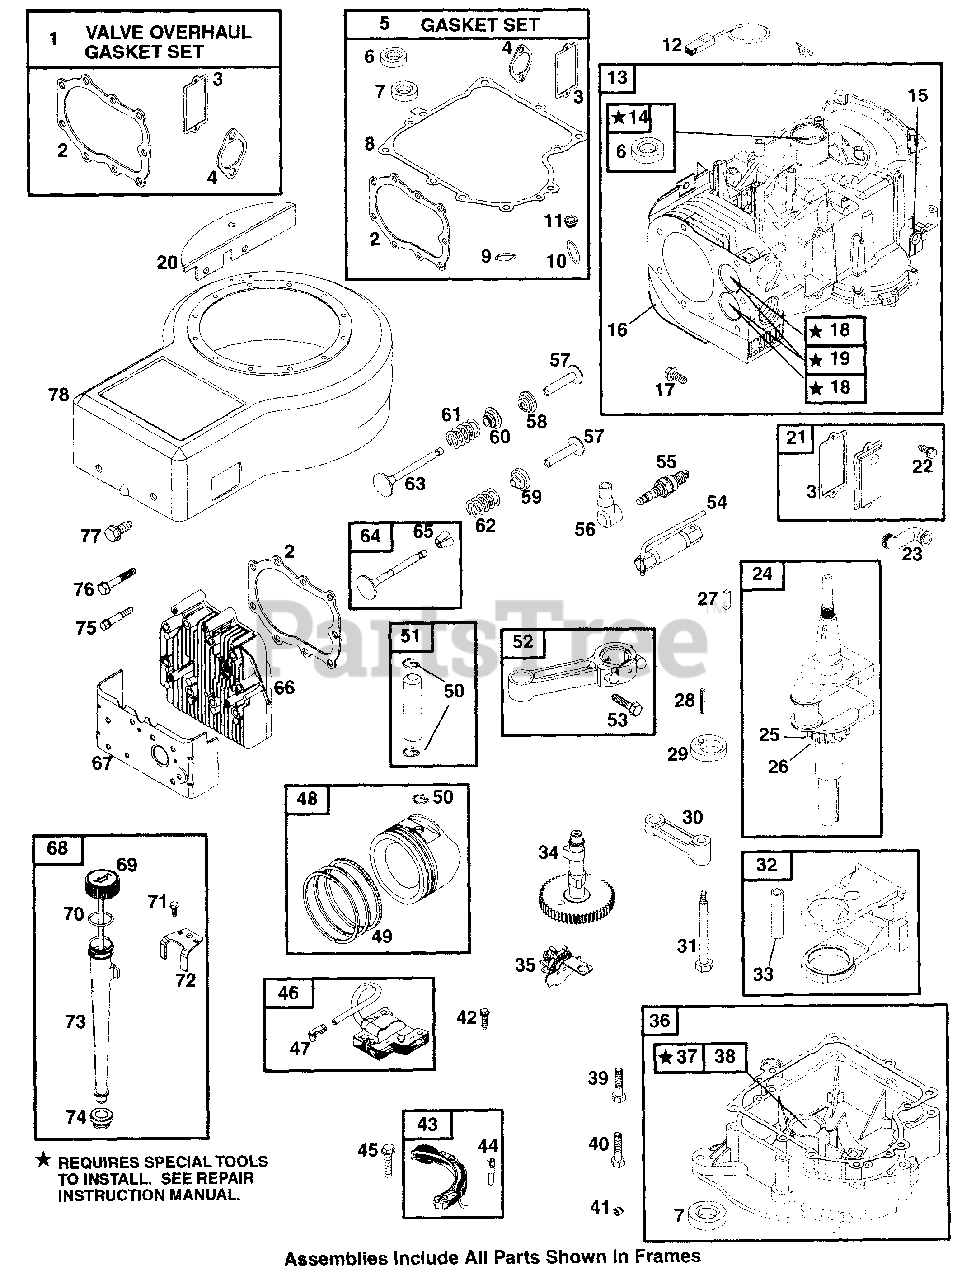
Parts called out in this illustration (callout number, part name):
1	Valve Overhaul Gasket Set
2	Cylinder Head Gasket
3	Breather Gasket
4	Intake Gasket
5	Gasket Set-Engine Overhaul
6	Oil Seal (Magneto Side)
7	Oil Seal (PTO Side)
8	Crankcase Gasket (.015" Thick)
9	O-Ring Seal (Dipstick)
10	O-Ring Seal (Air Cleaner Base)
11	Dipstick Tube Seal
13	Cylinder Assembly
14	Bushing/Seal Kit (Magneto Side)
15	Bushing-Gov. Crank
16	Shield-Cylinder
17	Screw (Cylinder Shield)
18	Seat-Valve
19	Bushing-Guide (Exhaust Valve)
20	Flywheel Guard
21	Breather Assembly
22	Screw (Breather Assembly)
23	Breather Tube
24	Crankshaft
25	Gear-Timing
26	Key-Timing
27	Flywheel Key
28	Pin-Retainer
30	Link-Counterweight
31	Screw (Counterweight)
32	Counterweight
33	Pin-Counterweight
35	Governor / Oil Slinger
36	Engine Sump
37	Bushing / Seal Kit (PTO Side)
38	Oil Seal (PTO Side)
39	Screw (Engine Sump)
40	Screw (Eng Sump)
41	Oil Drain Plug
42	Screw (Magneto Armature)
43	Alternator
44	Wire-Alternator
45	Screw (Alternator)
46	Armature-Magneto
47	Terminal-Cable
48	Piston Assembly (Standard)
49	Ring Set (Standard)
50	Piston Pin Lock
51	Piston Pin (Standard)
52	Connecting Rod
53	Screw (Connecting Rod)
54	Wrench -Sparkplug
56	Boot-Sparkplug
57	Valve Tappet
58	Valve Retainer
59	Valve Retainer
60	Seal-Valve
61	Valve Spring (Exhaust)
62	Valve Spring (Intake)
63	Intake Valve
64	Exhaust Valve
65	Valve Keeper
66	Cylinder Head
67	Cover-Cylinder Head
68	Dipstick/Tube Assembly
70	O-Ring Seal (Dipstick)
71	Screw (Oil Fill Bracket)
72	Bracket-Oil Fill
73	Dipstick Tube
74	Dipstick Tube Seal
75	Screw (Cylinder Head Cover)
76	Screw (3" Long) (Cylinder Head)
77	Screw (Blower Housing)
78	Housing-Blower
